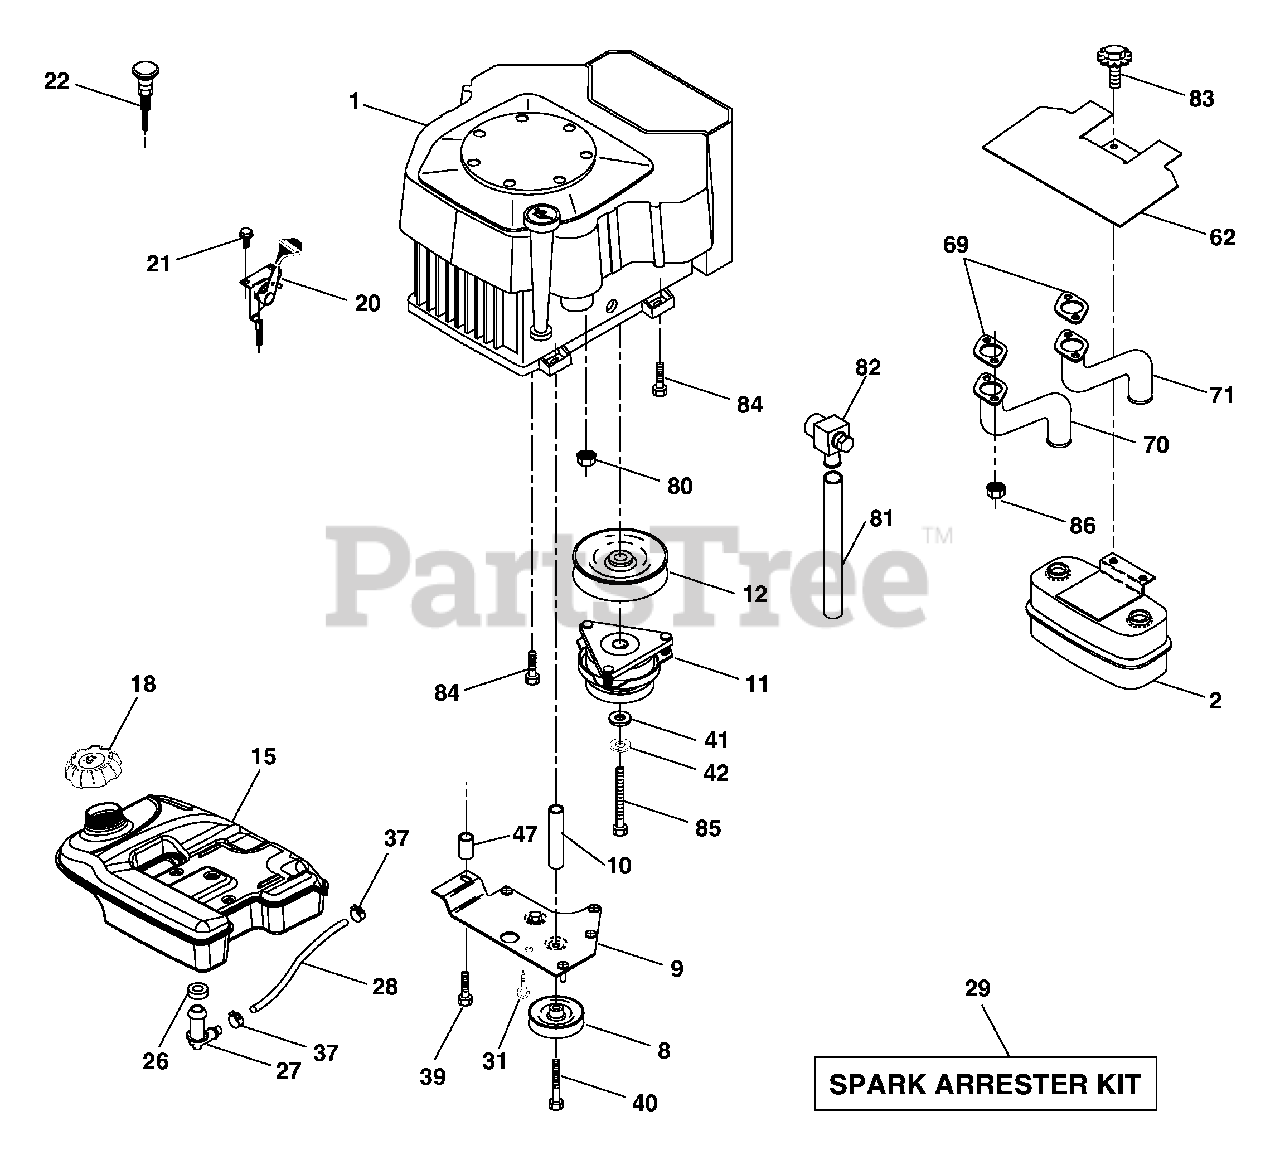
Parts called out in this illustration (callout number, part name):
2	Muffler Side
8	Pulley V-Idler
9	Keeper Asm. Belt Engine VGT
10	Bushing
11	Clutch Electric
12	Pulley Engine VGT Elect Clutch
15	Tank Fuel Rear 5.0
18	Cap Asm. Fuel
20	Control Throttle
21	Screw 10 x 3/4 Single Lead Hex
22	Control Choke
26	Bushing
27	Stem Tank Fuel
29	Spark Arrester Kit
31	Clip
37	Clamp Hose
39	Screw TT 3/8-16 x 2-1/4 unc
40	Screw TT 3/8-16 x 4 unc
41	Washer 1-1/2 OD x 15/32 ID x .250
42	Washer Lock 7/16
47	Spacer
62	Shield Heat Muffler CV-Intek
69	Gasket (Order from Engine Mfgr.)
70	Tube Exhaust LH
71	Tube Exhaust RH
79	Screw Socket Head 5/16-18 x 1
80	Nut Flange M8-1.25
81	Tube Drain Oil
82	Valve Oil Drain
83	Bolt 5/16-18 Unc x 1-3/4 W/Sems
84	Screw Thdrol 3/8-16 x 1-1/2
85	Bolt Hex 7/16-20 x 3.75 Gr. 5
86	Nut Hex Flange Toplock M8-1.25
